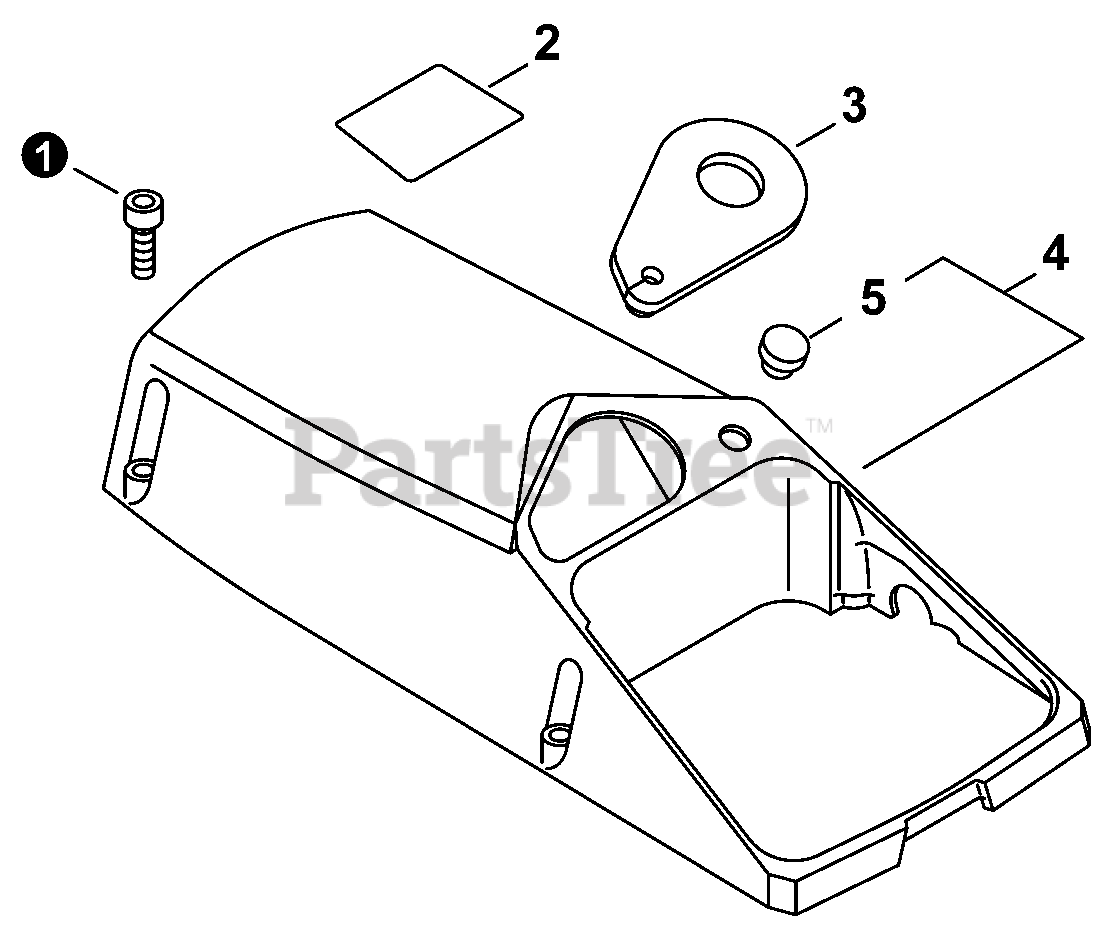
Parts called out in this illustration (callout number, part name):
1	BOLT 5x20
2	LABEL - CAUTION - KICK BACK
3	PLATE, GUIDE
4	ENGINE COVER KIT - GRAY
4	ENGINE COVER KIT - ORANGE
